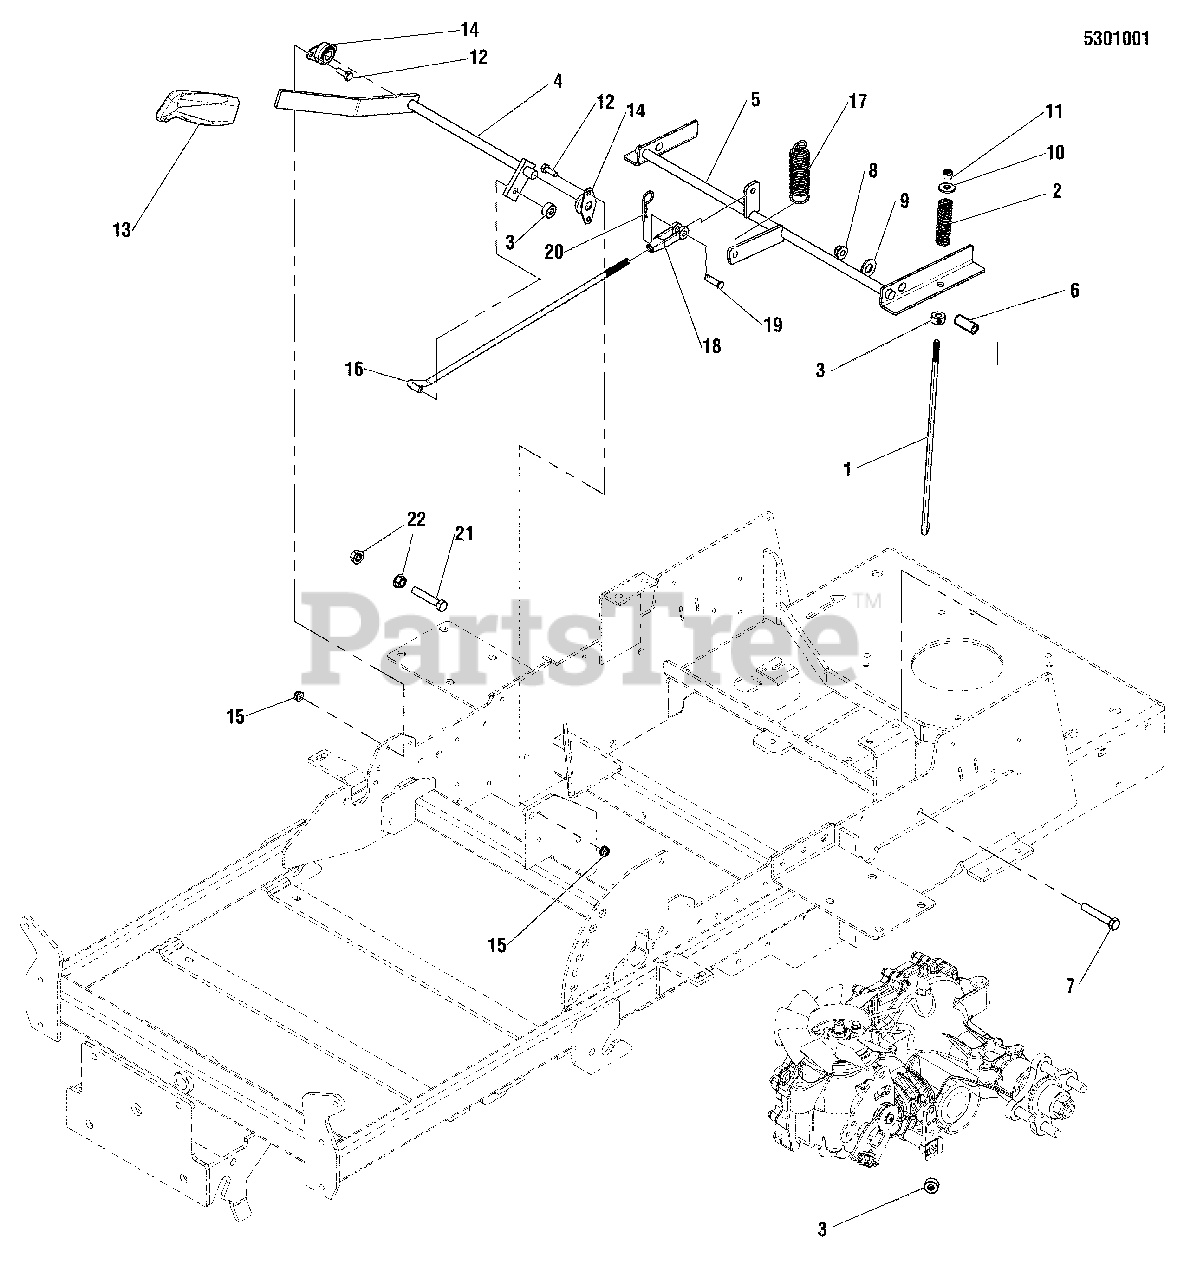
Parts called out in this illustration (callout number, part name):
1	ROD, BRAKE CTRL, LOWER - CONZ
2	SPRING, COMPRESSION
3	COLLAR, 5/16" SET
4	WELD, SHAFT, BRAKE HANDLE - RED
5	WELD, BRAKE SHAFT - RED
6	SPACER, .38 X .50 X 1.56
7	BOLT, 3/8-16 X 2-1/4" GD5 CZ
8	NUT, 3/8-16 HEX NYLOCK FLANGE
9	WASHER, 1/2 SAE
10	WASHER, 5/16 USS
11	NUT, 5/16-24 HEX NYLON LOCK
12	BOLT, 1/4-20 X 3/4 GD5 YZ
13	GRIP, BLACK FLEXIBLE
14	BEARING, 1/2" FLANGED
15	NUT, 1/4-20 HEX NYLOCK FLANGE
16	ROD, PULLER ROD
17	SPRING, EXTN 1.040ODX 04.000LG .105WIRE D
18	CLEVIS, 5/16-24, STEEL
19	PIN, CLEVIS, 5/16 X 1 YZ
20	PIN, HAIR, .0915 X 1-7/8
21	BOLT, 3/8-16 X 2, GD5, CZ
21	BOLT, 3/8-16 X 2-1/4" GD5 CZ
22	NUT, 3/8-16 HEX SERRATED FLANGE
